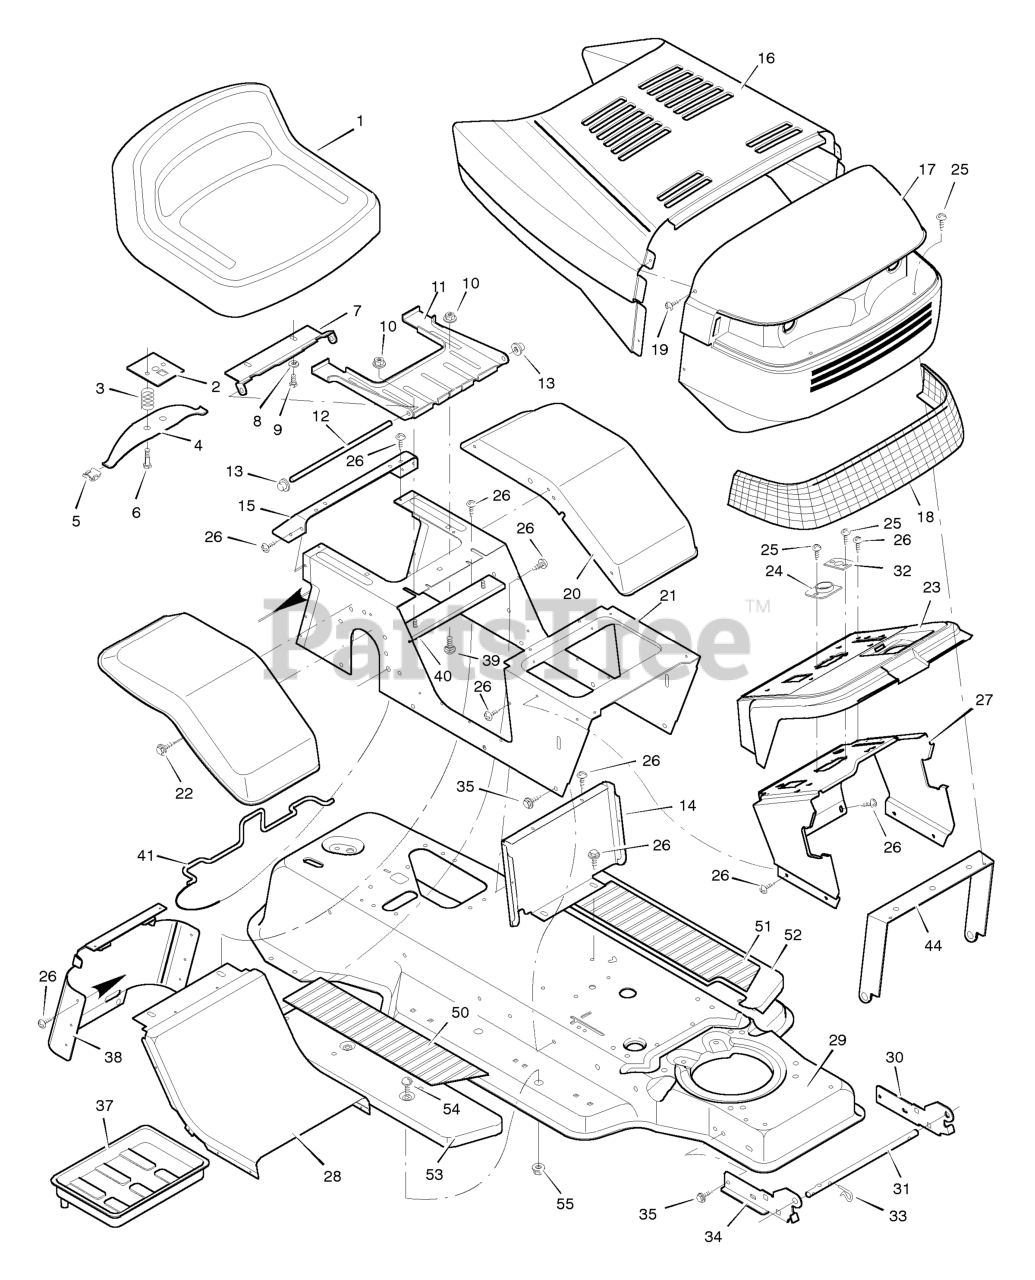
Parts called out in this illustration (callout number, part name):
2	Plate Assembly, Switch
3	Spring, Compression
4	Spring, Seat
5	Glide, Spring
6	Bolt, Shoulder
7	Support, Seat
8	Lockwasher
9	Bolt, Hex
10	Locknut, Flange
11	Bracket, Pivot
12	Rod, Pivot
13	Cap, Push On
14	Insert, Front
15	Fender, Apron
16	Hood
17	Grille Assembly
21	Console Assembly
23	Dash Panel
24	Bearing, Steering
26	Screw
27	Support, Dash
28	Insert, Rear
29	Frame Assembly
30	Bracket, Left Grille
31	Rod, Pivot
32	Bearing
33	Pin, Hair
34	Bracket, Right Grille
37	Tray, Battery
38	Cap, Console
39	Bolt
40	Channel Assembly
41	Clamp, Battery
44	Brace, Grille
50	Mat, Right
51	Mat, Left
52	Running Board, Left
53	Running Board, Right
54	Bolt, Carriage
55	Nut, Flange
